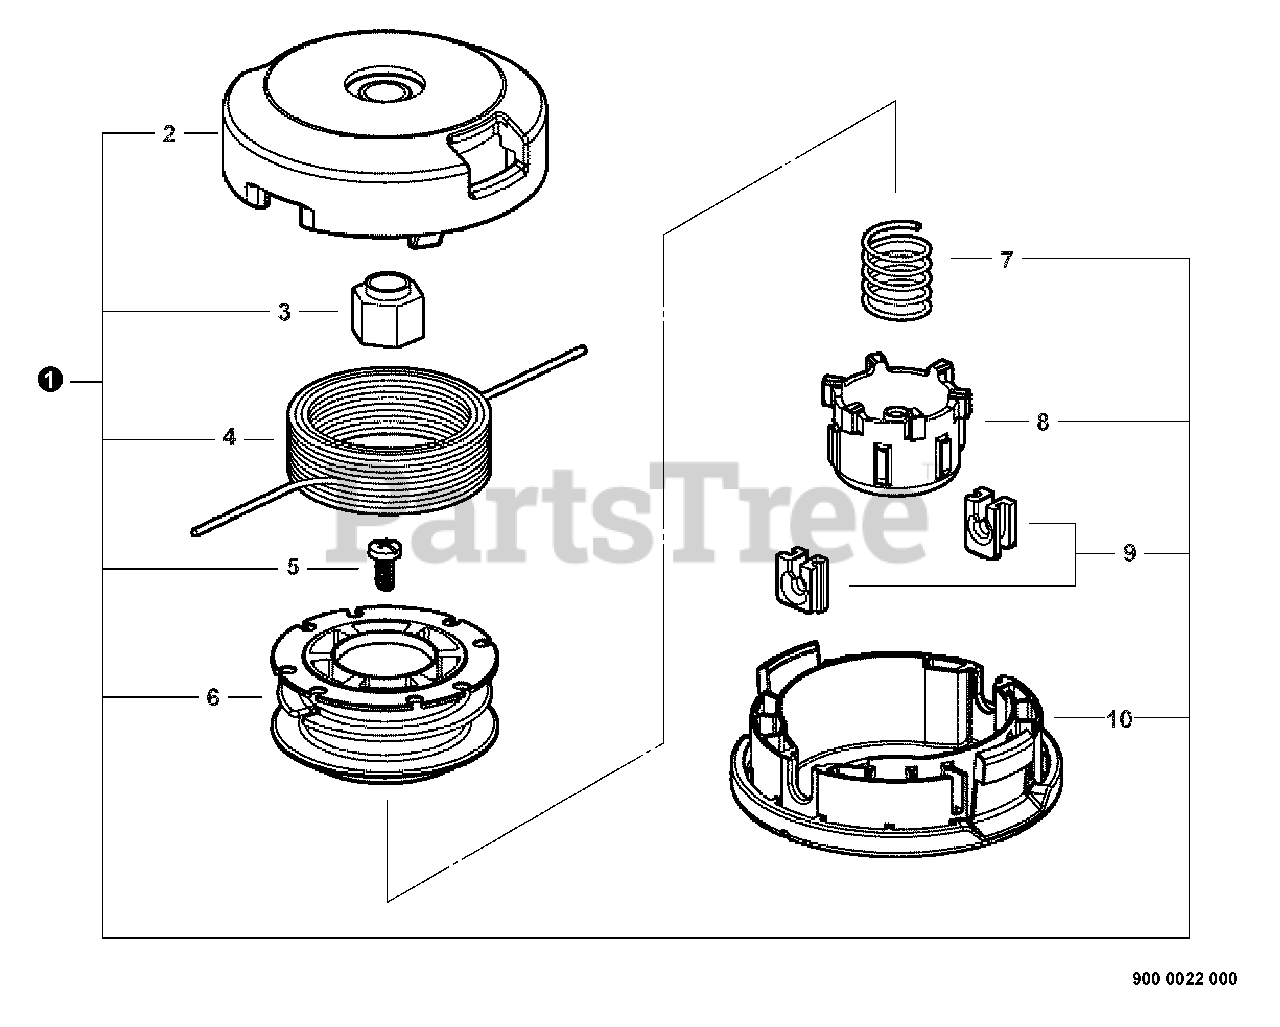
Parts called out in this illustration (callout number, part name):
1	TRIMMER HEAD G137
2	COVER, SPOOL
3	BUSHING
4	LINE, NYLON TRIMMER
10	HOUSING, SPOOL
